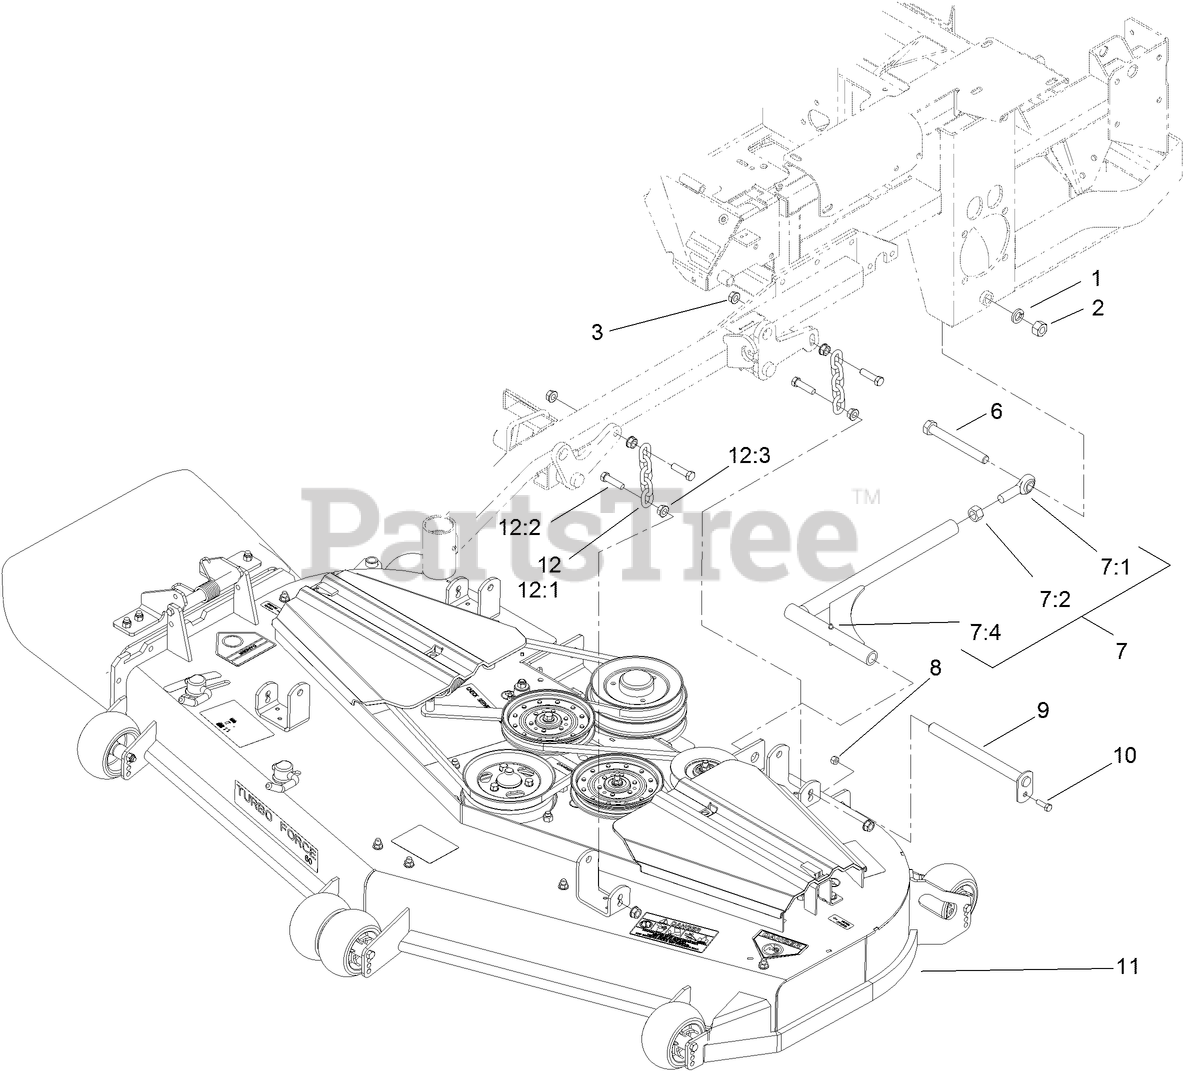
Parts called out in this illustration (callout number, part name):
1	WASHER-LOCK
2	NUT-HEX
3	NUT-HF
6	SCREW-HH
7	STRUT ASM
7:1	BALLJOINT-SPHERICAL
7:2	NUT-HEX
7:4	FITTING-GREASE
8	NUT-LOCK, NI
9	PIN-STRUT
10	SCREW-HH
11	DECK ASM
12	DECK CHAIN ASM
12:1	CHAIN-LIFT, DECK
12:2	SCREW-HH
12:3	NUT-HF
